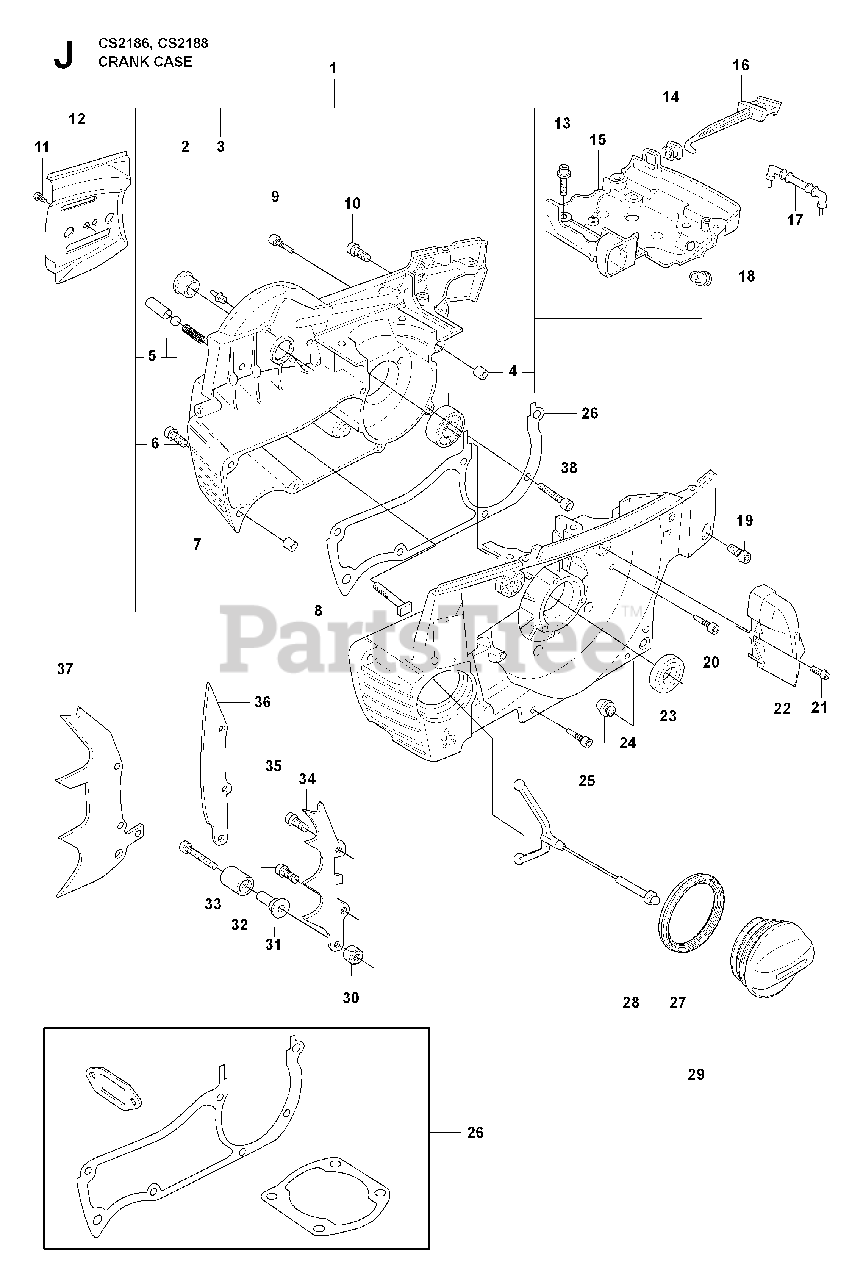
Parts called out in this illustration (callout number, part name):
1	CRANKCASE
2	BUSHING
3	PIN
4	SLEEVE
5	VALVE
6	%SCREW
7	SLEEVE
8	BOLT
16	CHOKE CONTROL
17	SPACER
19	%SCREW
23	SEALING RING
26	GASKET SET
27	SEALING
28	HOLDER
29	TANK CAP
34	FELLING DOG
37	FELLING DOG
